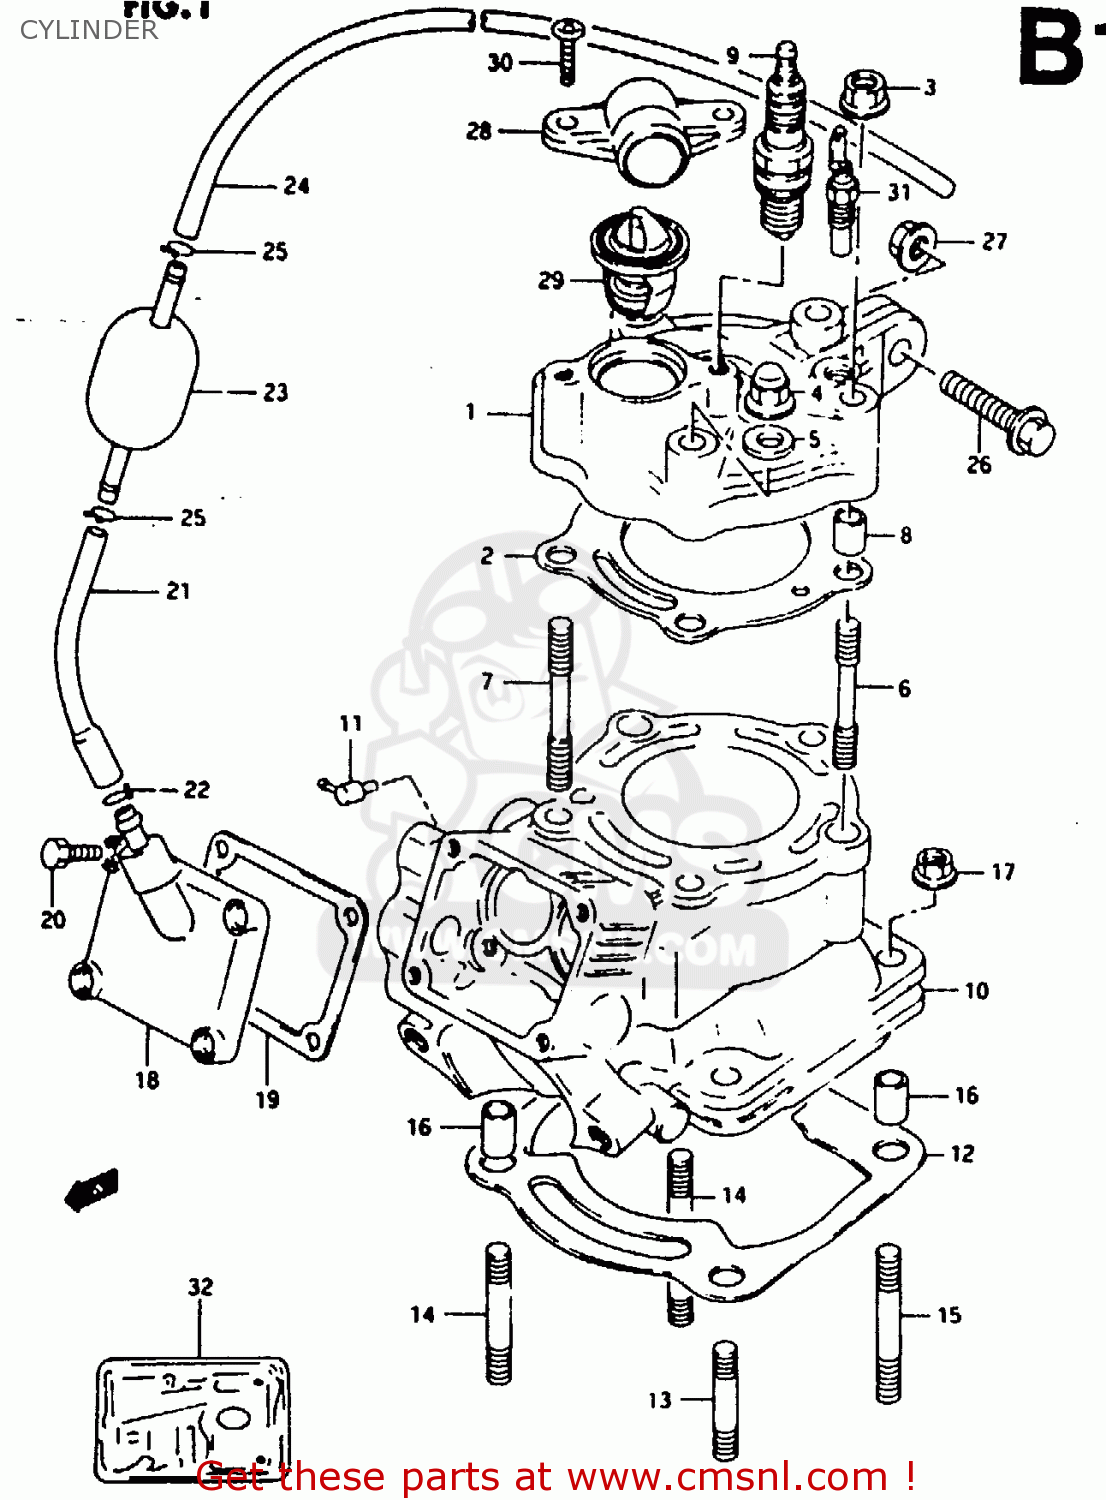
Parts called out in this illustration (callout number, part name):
1	HEAD,CYLINDER
2	GASKET,CYLINDER HEAD (NAS)
3	NUT
4	NUT
5	GASKET(8.5X17X2.3) (NAS)
6	STUD BOLT (L:45)
7	BOLT,HEAD STUD
8	PIN
9	PLUG,SPARK(BR9ECM)
10	CYLINDER
11	VALVE,OIL HOSE CHECK
12	GASKET,CYLINDER (NAS)
13	BOLT,STUD
14	BOLT,STUD
15	BOLT,STUD
16	PIN
17	NUT
18	COVER,CYLINDER
19	GASKET,CYL COVER NO.2 (NAS)
20	BOLT
21	HOSE (5X8.2X300)
22	CLIP
23	VESSEL,SILENCER
24	HOSE
25	CLIP
26	BOLT
27	NUT
28	COVER,THERMOSTAT
29	THERMOSTAT COMP,WATER
30	SCREW
31	GAUGE,WATER,TM
32	GASKET SET (NAS)
